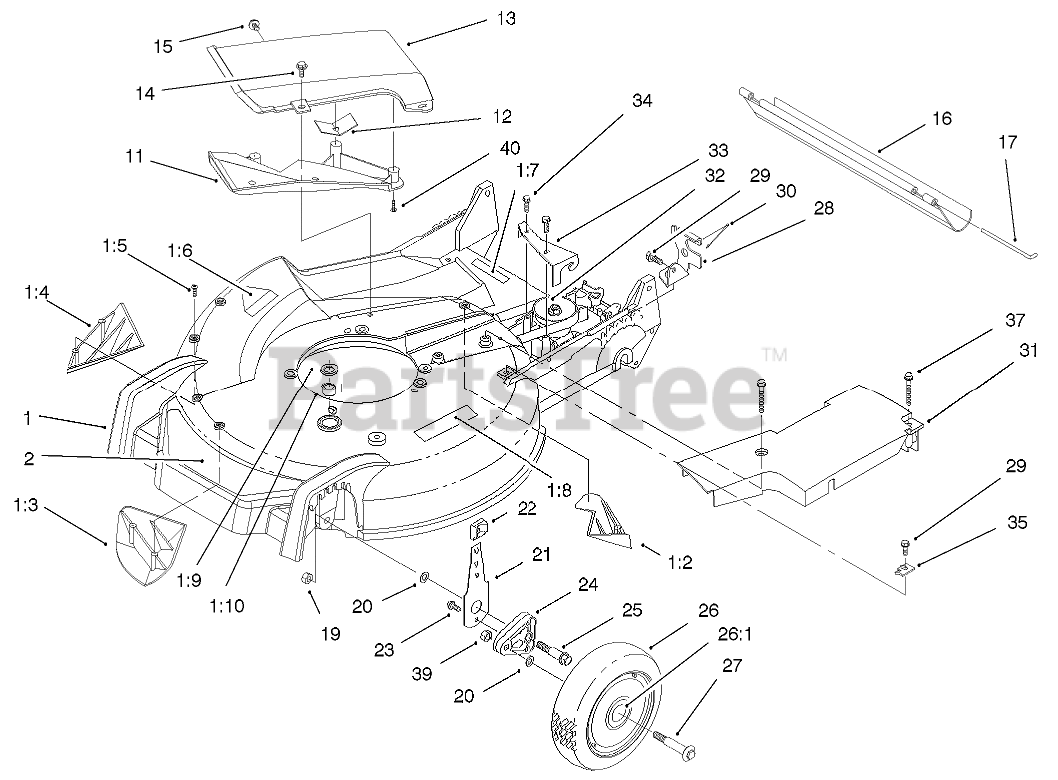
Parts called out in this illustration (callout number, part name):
1	HOUSING
1:2	KICKER-REAR
1:3	KICKER-FRONT
1:4	KICKER-RH
1:5	SCREW-PPH
1:6	DECAL-DANGER
1:7	DECAL-WARNING
1:8	DECAL-WARNING
1:9	WASHER
1:10	BEARING
2	DECAL - DECK
11	Deflector-Recycler
12	Guard-Cover
13	COVER W/DEFLECTOR
14	SCREW-HWH
15	SCREW AND WASHER ASM
16	SHIELD-TRAILING
17	ROD-SHIELD
19	NUT-LOCK
20	WASHER
21	FRONT SPRING ARM ASM
22	KNOB-ARM
23	SCREW-HWH
24	ARM-PIVOT, FRONT
25	BOLT-SHOULDER
26	WHEEL ASM
26:3	BUSHING
27	BOLT-SHOULDER
28	BRACKET-TRACTION, ADJ.
29	SCREW-HWHTF
30	RETAINER-CABLE
31	COVER-BELT
32	GEARCASE ASM
33	BRACKET-GUIDE, BELT
34	SCREW-HWHTF
35	CLAMP-CABLE
37	SCREW-HHFTF
40	Screw-PPH
